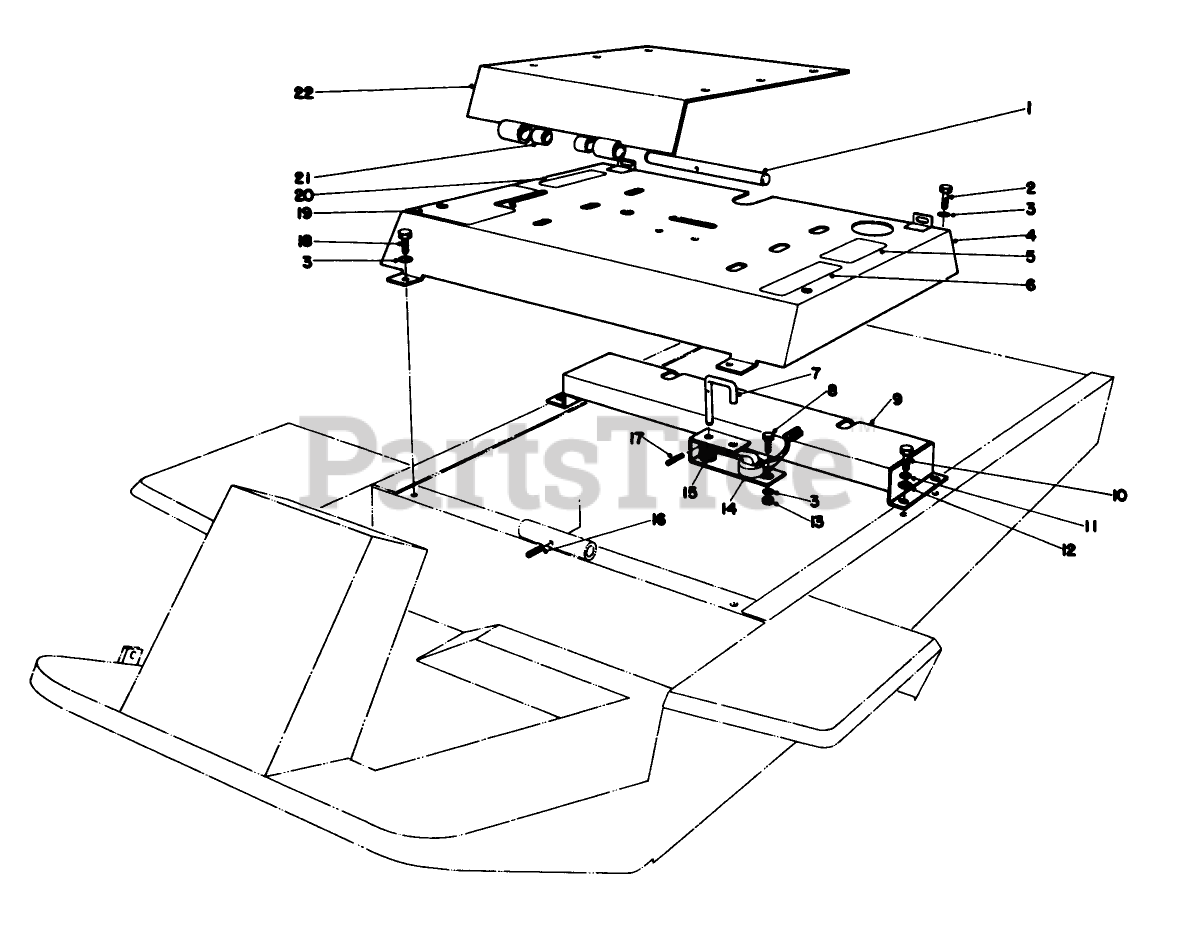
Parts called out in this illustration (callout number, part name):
1	SHAFT-PIVOT, SEAT
2	SCREW-HH
3	WASHER-LOCK
4	Cover-Seat Support (Incl. Ref. #5, 6, 19 & 20)
5	DECAL-REFUELING
6	Decal Caution
7	SEAT SWITCH PIN
8	SCREW-HH
9	Seat Support
10	SCREW-HH
11	WASHER-LOCK
12	WASHER-FLAT
13	NUT-HEX
14	SEAT SWITCH
15	SPRING
16	PIN-ROLL, SLOTTED
17	PIN-SPRING
18	SCREW THD 1/4 20 5/8
19	Decal Hydraulic Lift
20	Decal Caution
21	.503ID X .875LG BSHG
22	Seat Mount (Incl. Ref. #21)
